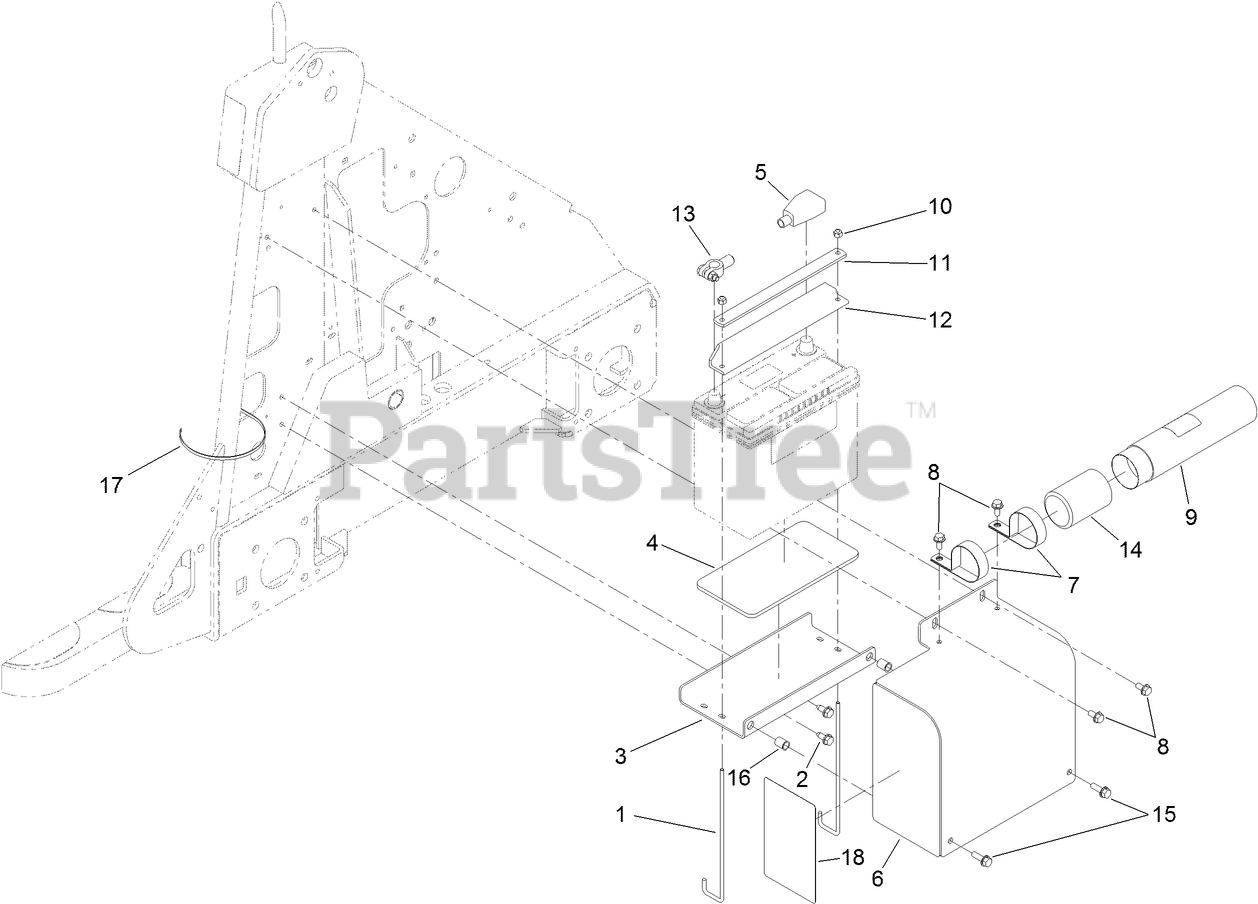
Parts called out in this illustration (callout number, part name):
1	RETAINER-BATTERY
2	SCREW-HWHTF
3	MOUNT-BATTERY
4	PAD-BATTERY
5	CABLE-BATTERY, POSITIVE
6	COVER-BATTERY
7	CLAMP-R
8	SCREW-HWHTF
9	TUBE-MANUAL
10	NUT-LOCK, NI
11	RETAINER-BATTERY
12	RETAINER-BATTERY
13	CABLE-BATTERY, NEGATIVE
14	CAP-HOUSING
15	SCREW-HHF
16	NUT-CLINCH
17	TIE-CABLE
18	DECAL-SERVICE
18	DECAL-SERVICE, FRENCH
18	DECAL-SERVICE, GERMAN
18	DECAL-SERVICE, SPANISH
18	DECAL-SERVICE, ITALIAN
18	DECAL-SERVICE, DUTCH
18	DECAL-SERVICE, POLISH
18	DECAL-SERVICE, RUSSIAN
18	DECAL-SERVICE, SLOVAKIAN
